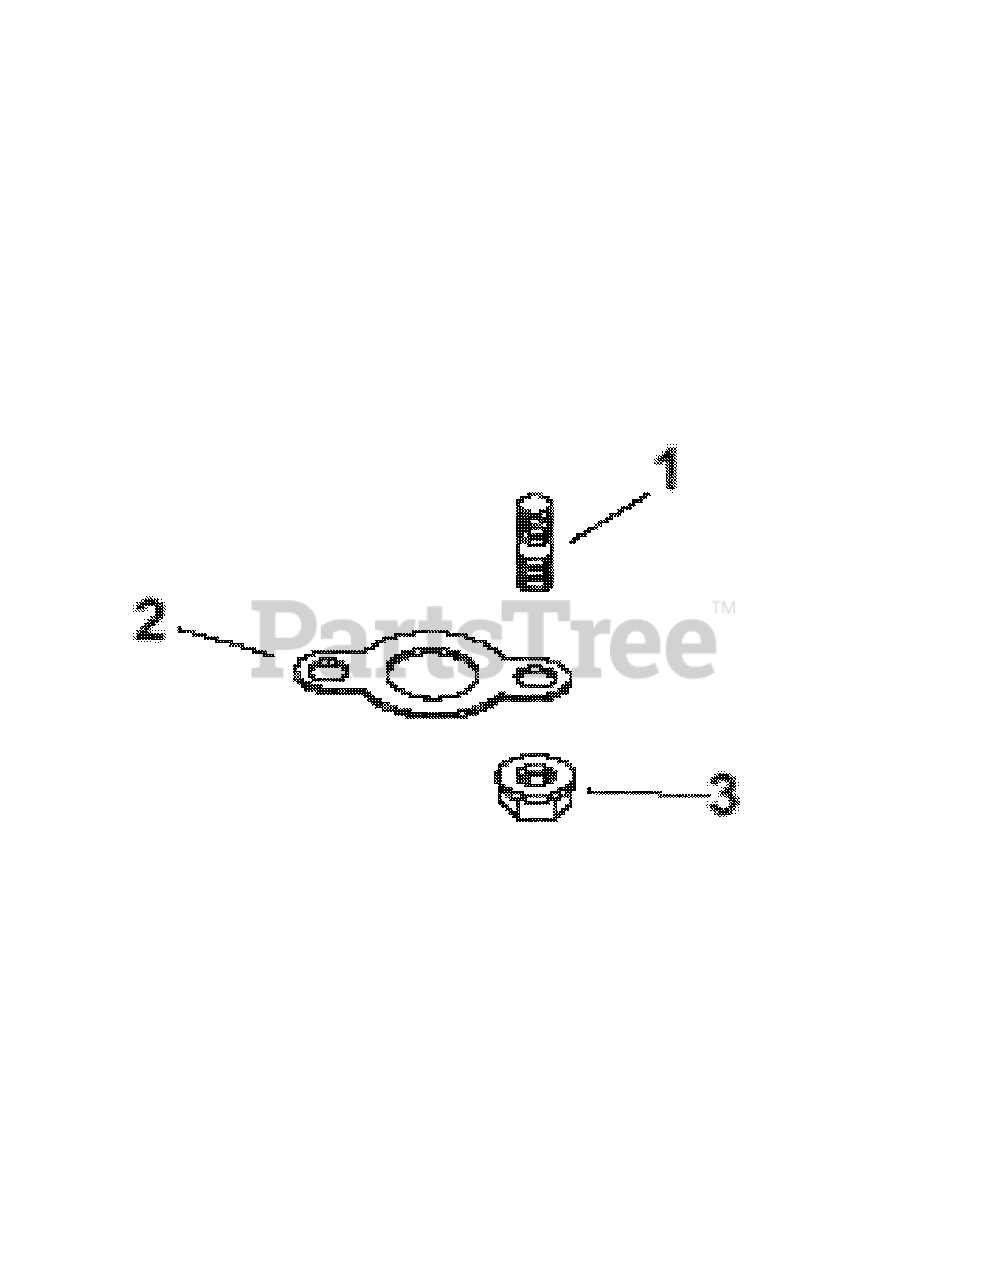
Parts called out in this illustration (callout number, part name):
1	Exhaust Stud
2	Exhaust Gasket
3	Hex Flange Nut
